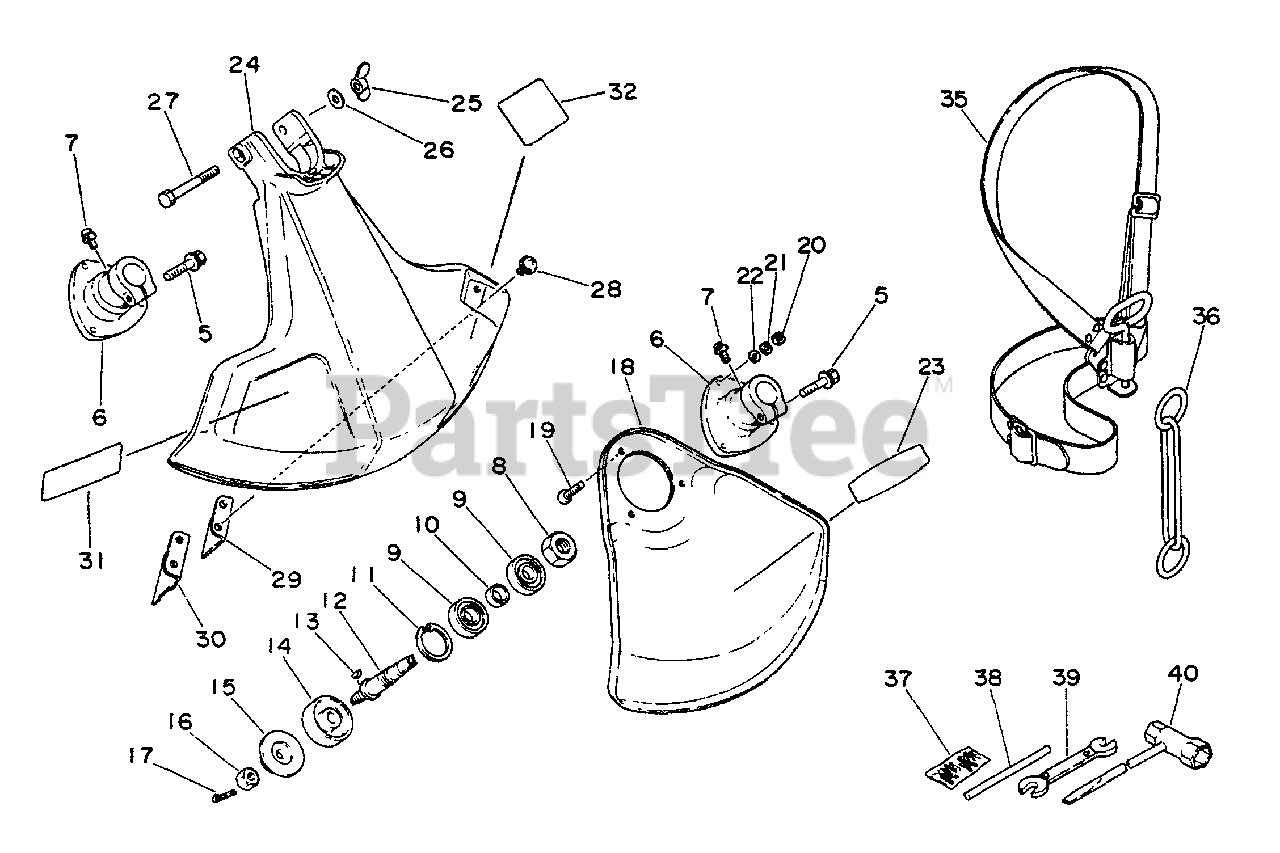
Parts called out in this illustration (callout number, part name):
5	BOLT - 5X25
6	GEAR CASE ASSY
6	CASE, BEARING
7	SCREW - 4X10
8	NUT - 12 -- LEFT HAND
9	BEARING, BALL - 6001 DDU
11	RING, RETAINING - 28
12	GEAR - SHAFT
14	ADAPTOR, BLADE - UPPER
15	ADAPTOR, BLADE - LOWER
16	NUT - 3/8-24
17	PIN, SPLIT - 2X22
18	SHIELD, DEBRIS
19	SCREW - 4X18
21	LOCKWASHER - 4
22	WASHER - 4
23	LABEL - ECHO
24	SHIELD, DEBRIS - PLASTIC
25	WINGNUT - 6
26	WASHER - 6
27	BOLT - 6X50
28	SCREW - 5X16
29	KNIFE, TRIMMER LINE
30	GUARD
31	LABEL - ECHO
32	LABEL - CAUTION
35	SHOULDER STRAP ASSY
37	PIN, SPLIT - 2X22
38	LOCKING TOOL
39	SPANNER - 8X10mm
40	T-WRENCH - 17X19mm
